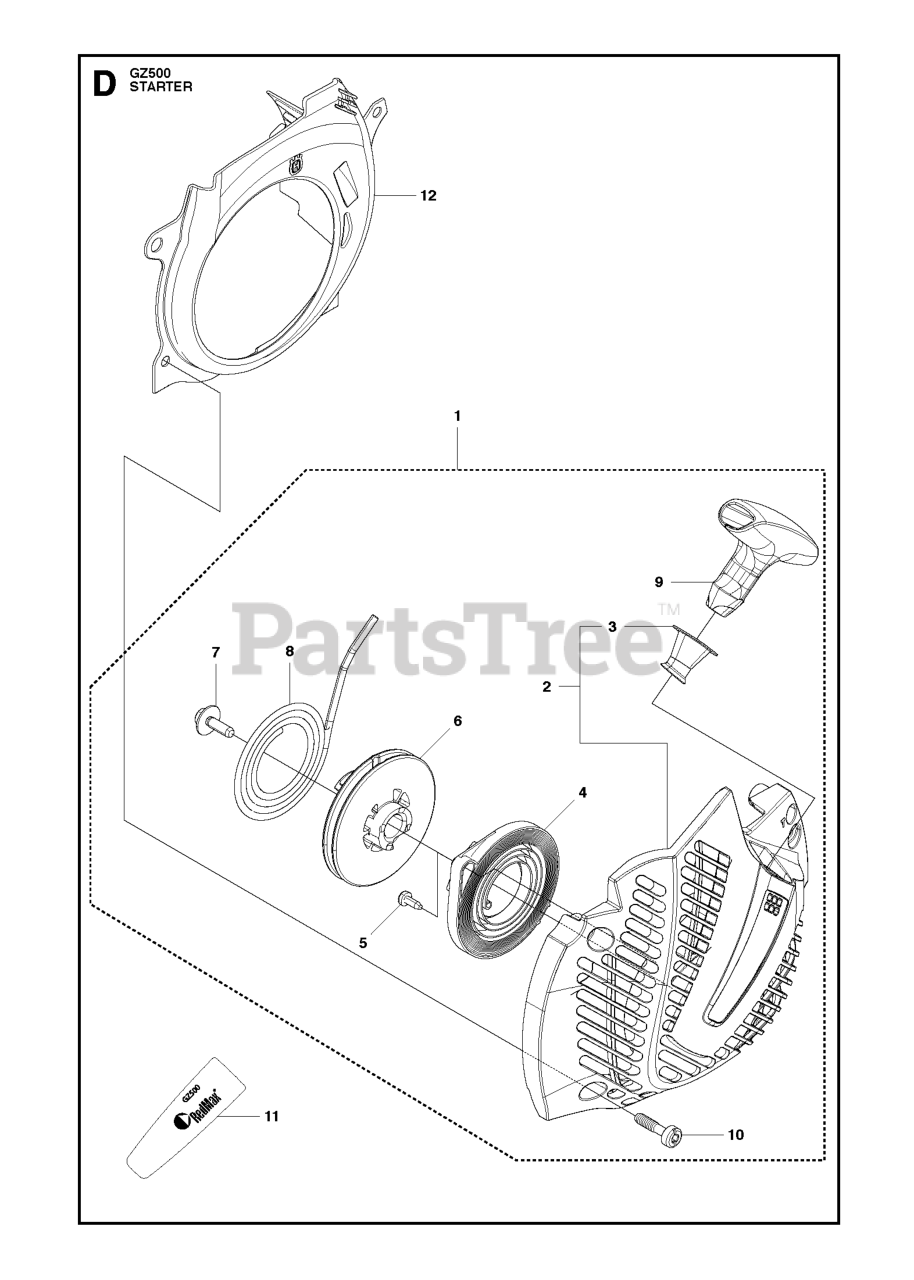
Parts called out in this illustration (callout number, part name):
1	STARTER ASSY
2	STARTER HOUSING
4	SPRING CASSETTE ASSY
5	SCREW CCRPANT
6	STARTER PULLEY
8	STARTER CORD
9	STARTER HANDLE
11	LABEL STARTER STANDARD REDMAX
12	COOLING AIR CONDUCTOR
